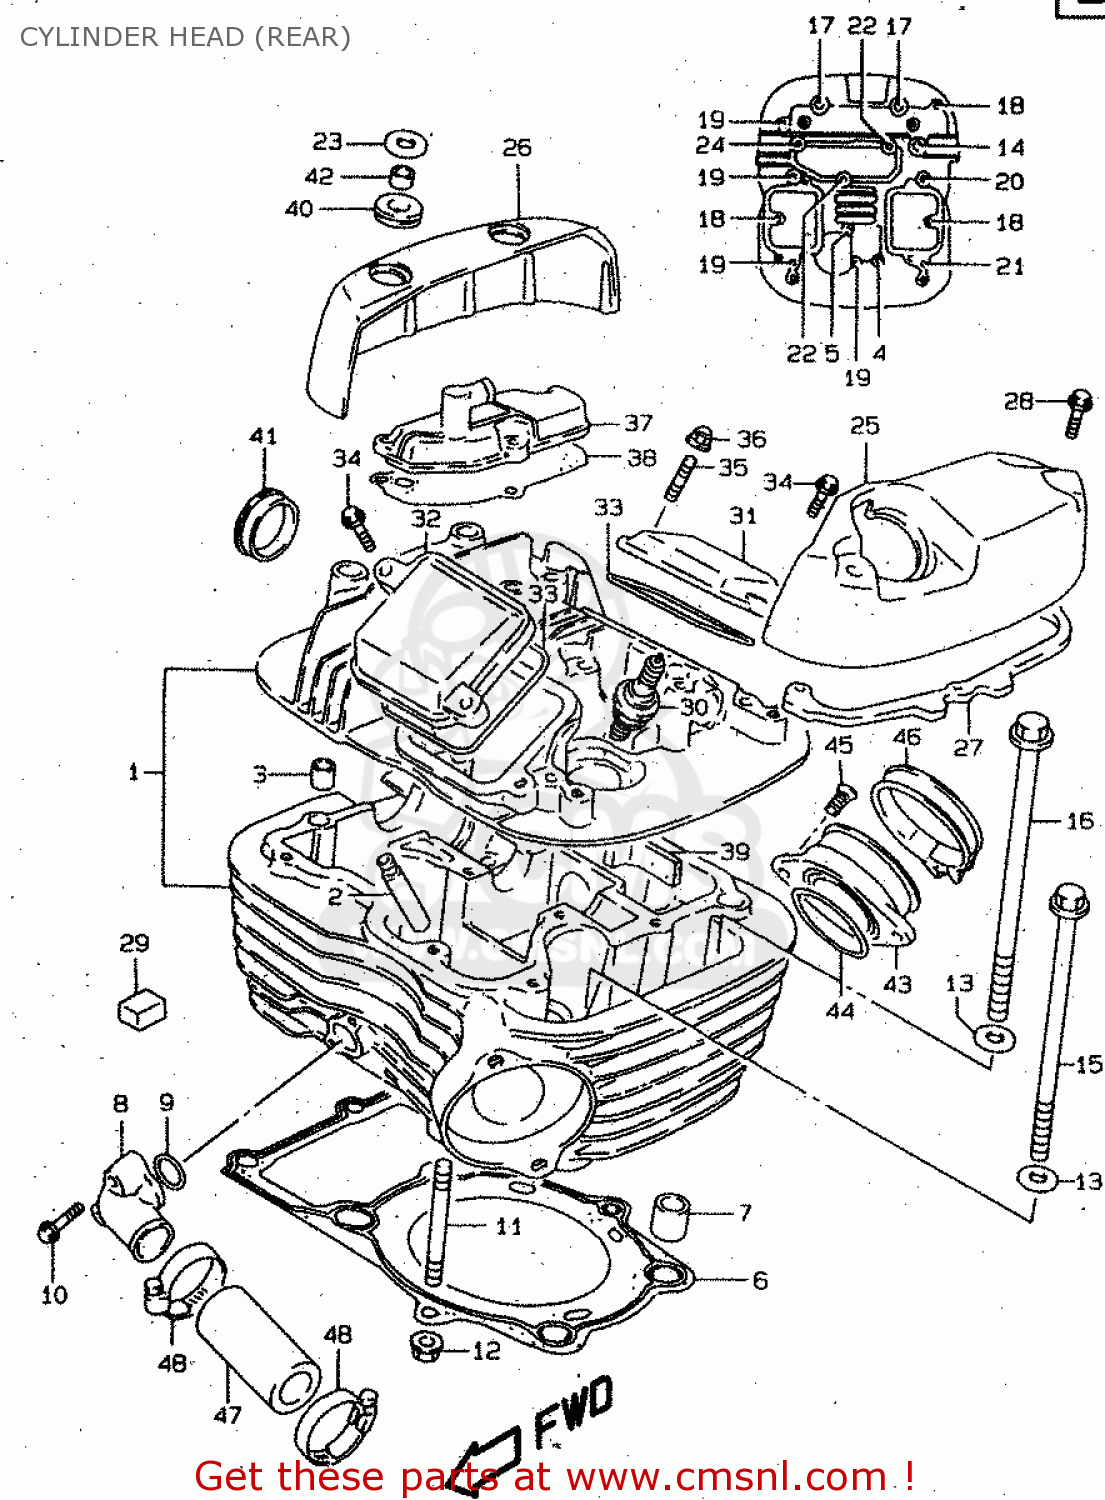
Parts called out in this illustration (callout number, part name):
1	HEAD ASSY,CYLINDER RR
2	GUIDE,VALVE
3	PIN(8.4X11X14)
4	BOLT(6X50)
5	BOLT(6X55)
6	GASKET,CYLINDER HEAD RR (NAS)
7	PIN
8	UNION,CYLINDER HEAD WATER
9	O RING(D:2.4,ID:17.8)
10	SCREW
11	BOLT,STUD
12	NUT
13	WASHER (10.5X22X2.3)
14	BOLT(8X140)
15	BOLT(10X155)
16	BOLT(10X165)
17	BOLT(8X245)
18	BOLT
19	BOLT
20	BOLT
21	BOLT
22	BOLT(6X55)
23	WASHER(8.5X24X1.6)
24	BOLT
25	CAP,CYLINDER HEAD COVER RR,L
26	CAP,CYLINDER HEAD COVER RR,R
27	CUSHION,RR,L CAP
28	BOLT
29	PAD
30	PLUG,SPARK(DPR8EA-9)
31	CAP,INSPECTION INTAKE
32	CAP,INSPECTION EXHAUST
33	GASKET,INSPECTION CAP (NAS)
34	BOLT
35	STUD 6X16
36	NUT
37	COVER,BREATHER
38	GASKET,BREATHER COVER (NAS)
39	PLATE,HEAD COVER RR
40	CUSHION
41	PLUG(OD:30)
42	BUSH
43	PIPE,INTAKE,REAR
44	O RING(D:2.4,ID:39.7)
45	SCREW
46	CLAMP
47	HOSE,CYLINDER HEAD JOINT
48	CLAMP
